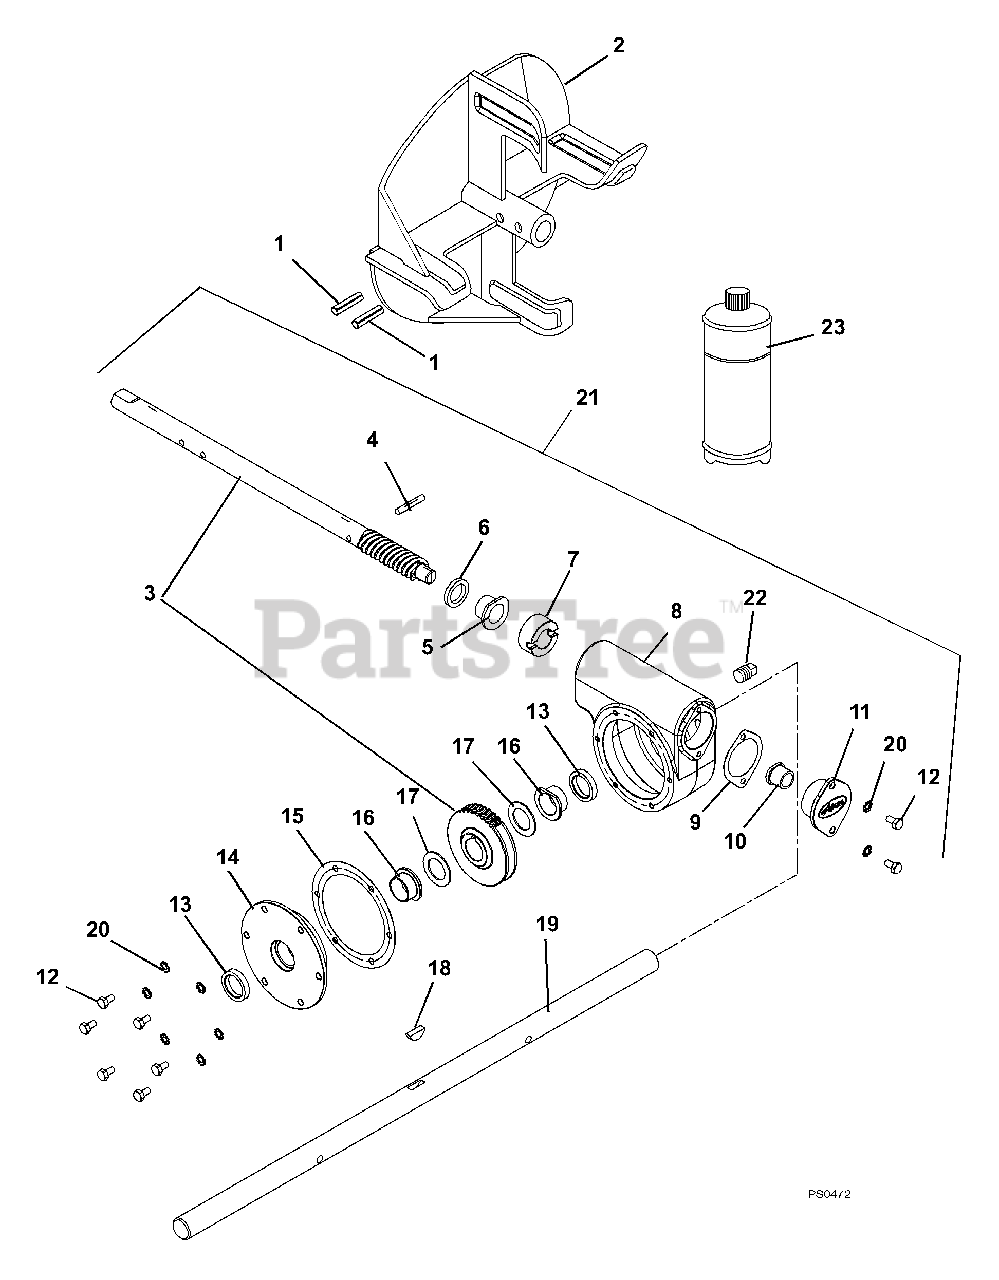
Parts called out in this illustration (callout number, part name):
1	PIN-ROLL .250X1.75
2	IMPELLER-14" 4 BLADE
2	IMPELLER-14" 6 BLADE
3	ASSY, WORM SHAFT & GEAR
4	PIN-GRV .250X1.50 TP E
5	BSHG-FLG .876 X 1.500 X .750
6	SEAL-OIL .875X1.25X.188
7	THRUST COLLAR, .875" ID
8	GEARCASE, CAST IRON-MACHINED
9	GASKET, FRONT - CAST IRON
10	BSHG-FLG .629 X 1.000 X .750
11	COVER, FRONT-CI GEARCASE
12	@BLT-HEX .25-20X.50 GR5 YWZC
13	SEAL-OIL 1.000X1.375X.250
14	COVER, SIDE-CI GEARCASE
15	GASKET, SIDE - CAST IRON
16	BSHG-FLG 1.003X1.5X.625
17	WSHR-HRD-THRS 1.007X1.542X.062
18	KEY-WDRF .25X.875X.375 SAE A
19	SHAFT, RAKE-26"
19	SHAFT, RAKE-28"
19	SHAFT, RAKE-32"
19	SHAFT, RAKE-36"
20	@WSHR-LK-EXT.262X.502X.026YWZC
21	GEAR CASE, CAST IRON-26"
21	GEAR CASE, CAST IRON-28"
21	GEAR CASE, CAST IRON-32"
21	GEAR CASE, CAST IRON-36"
22	PIPE PLUG, 1/4 NPT
23	ARIENS 16 OZ.BOTTLE OF L2 LUBE
